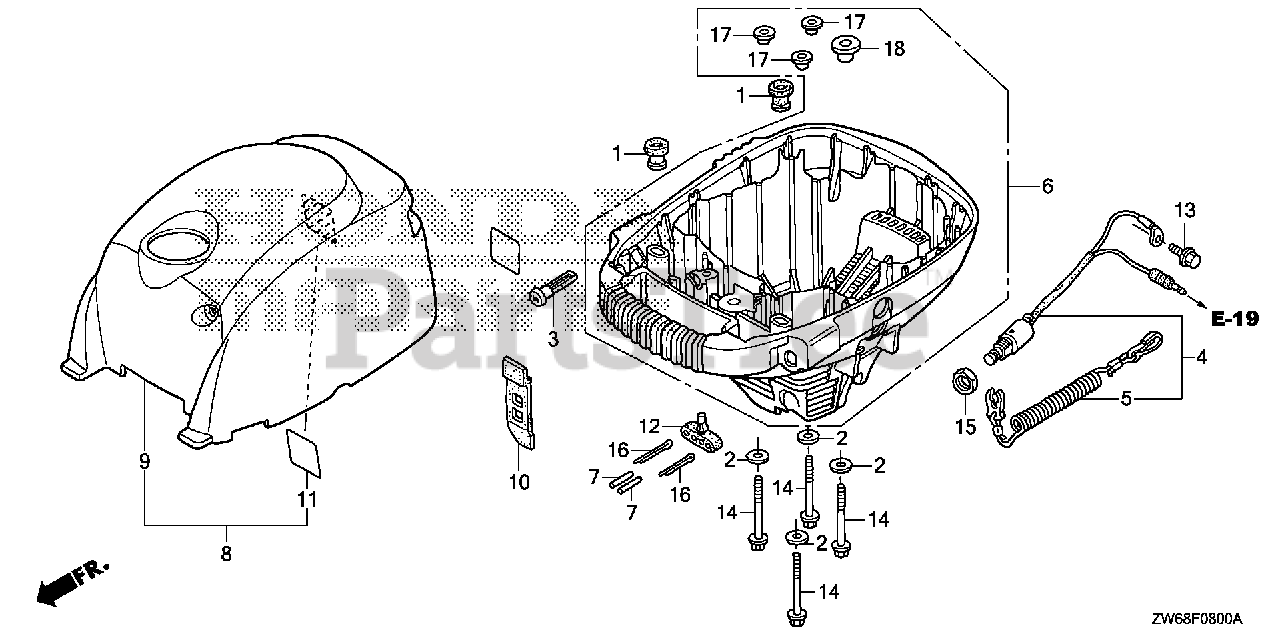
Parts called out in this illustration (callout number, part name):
1	RUBBER, TANK MOUNTING (C)
2	WASHER, PIVOT
3	KNOB, CHOKE
4	SWITCH ASSY., EMERGENCY STOP
5	WIRE, EMERGENCY
6	CASE, ENGINE (LOWER)
7	PIN, SHEAR
12	HOLDER, PARTS
13	BOLT, FLANGE (5X10) (CT200)
14	BOLT, FLANGE (6X60)
15	NUT, HEX. (16MM)
16	PIN, SPLIT (3MM)
16	PIN, SPLIT (3.0)
17	COLLAR (6X4)
18	COLLAR, ENGINE CASE (LOWER)
